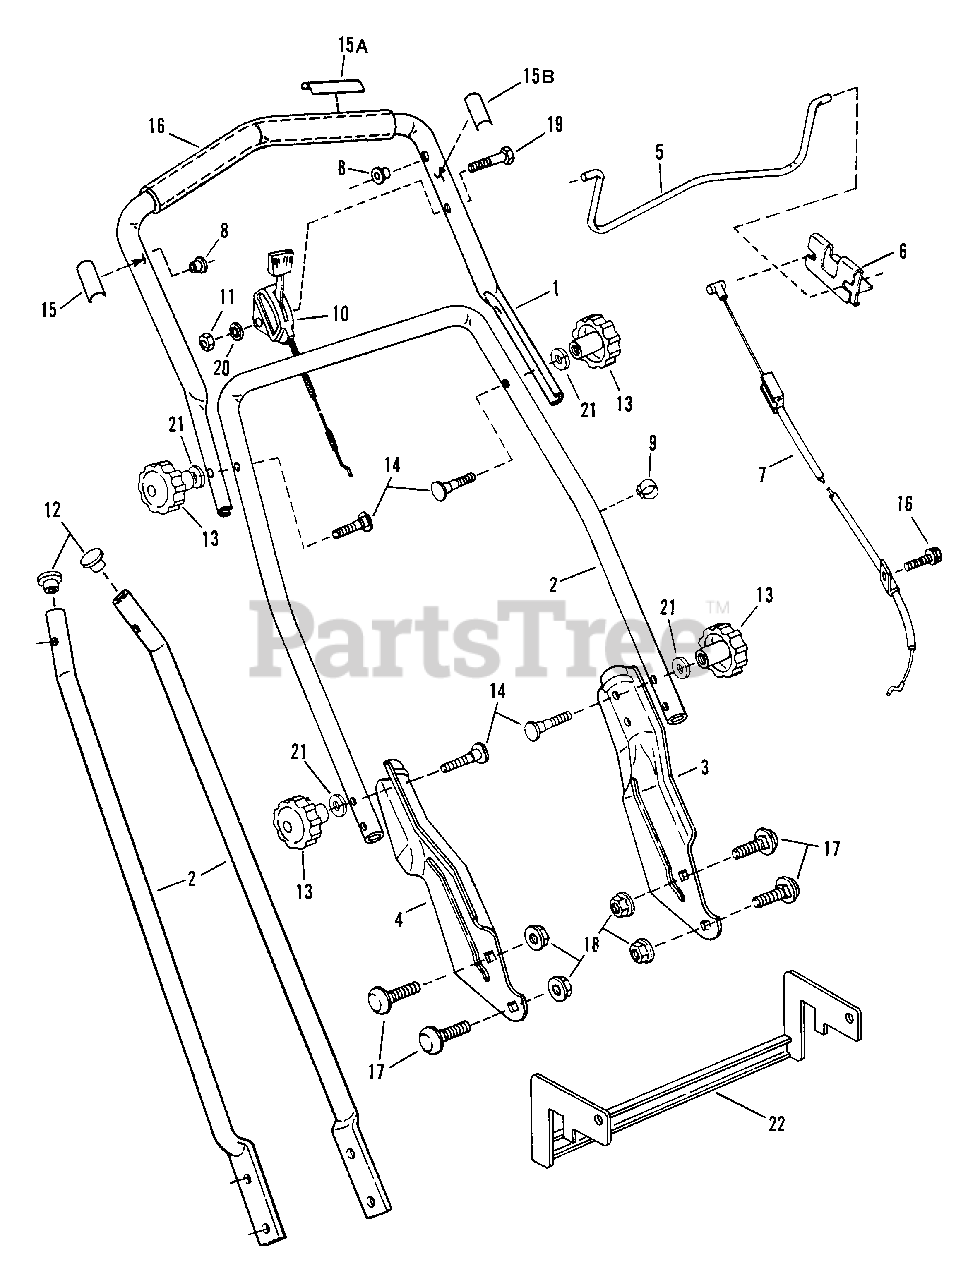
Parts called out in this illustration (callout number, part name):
1	HANDLE, Upper
2	HANDLE, Middle
3	HANDLE, Lower Left Hand
4	HANDLE, Lower Right Hand
5	CONTROL, Blade
6	CLIP, Blade Control
7	CABLE, Blade Control (Briggs & Robin 4-Cycle)
8	BUSHING
9	CLIP, Wiring Harness
10	CONTROL, Throttle (Briggs & Robin 4-Cycle)
11	NUT, 1/4-28 Hex
12	PLUG
13	KNOB, 5/16-18
14	SCREW, 5/16-18 x 2" Curved Head
15	DECAL, Blade Control
15A	DECAL, Blade Control
15B	DECAL, Blade Control
16	SCREW, #10-32 x 5/16" Sems
17	BOLT, 5/16-18 x 5/8" Short Neck Carriage
18	NUT, 5/16-18 Hex Flange Lock
19	SCREW, 1/4-28 x 2" Hex Head Cap
20	WASHER, 1/4 Internal Tooth Lock
21	WASHER, 5/16 Internal Tooth Lock
22	FENDER, Weldment Structure
